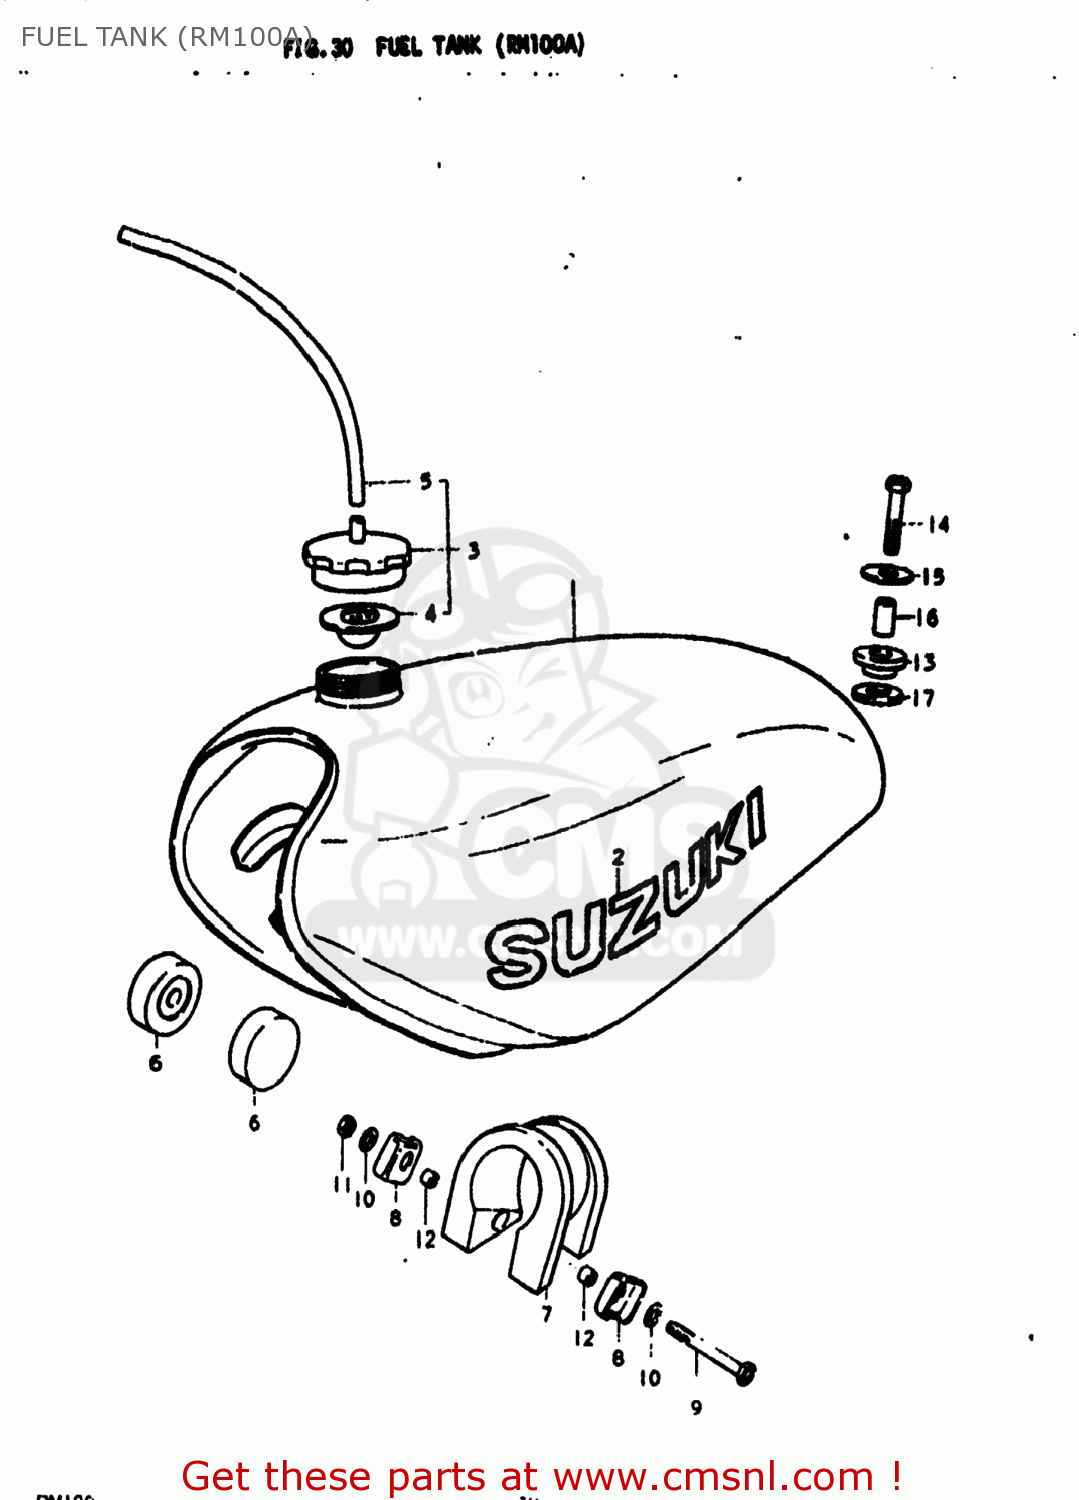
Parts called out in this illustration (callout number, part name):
1	TANK ASSEMBLY,FUEL
2	EMBLEM
3	CAP ASSY,FUEL TANK FILLER
4	GASKET,FUEL TANK CAP (NAS)
5	HOSE
6	CUSHION
7	CUSHION,FUEL TANK,REAR
8	CLIP
9	BOLT
10	WASHER 6MM
11	NUT
12	SPACER (6.1X8X5.2)
13	CUSHION
14	** SUPERSEEDED
15	WASHER
16	SPACER
17	CUSHION
